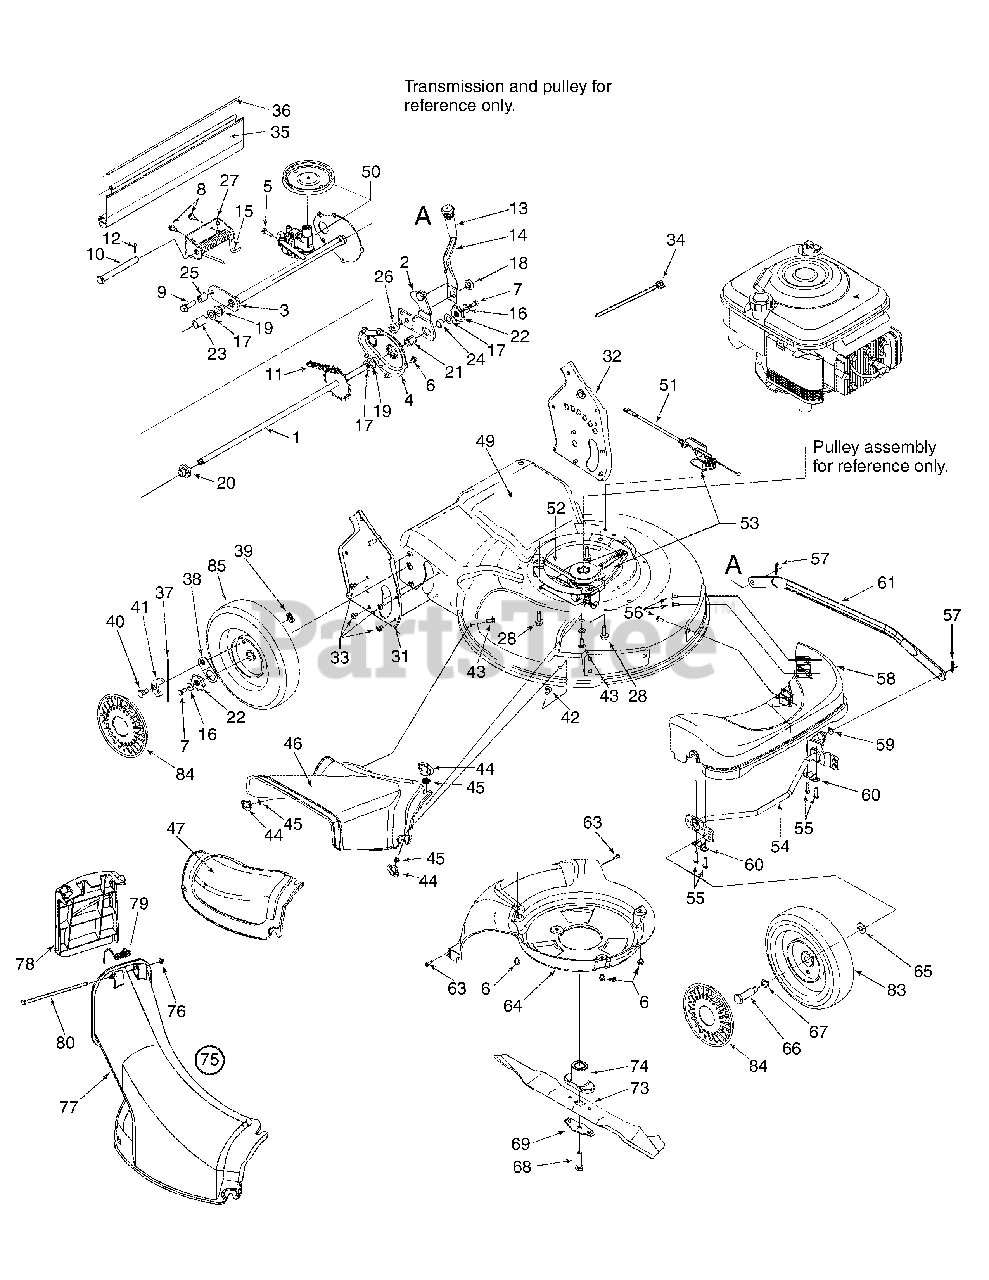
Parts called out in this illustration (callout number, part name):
1	Axle Ass’y 20T x 21.46" Lg.
6	Hex Wash HD Tapp Scr 1/4-20 x .38
7	Hex Bolt 1/4-20 x .62
8	Hex Wash HD. TT Tap Scr. 1/4-20 x .62
9	TT Screw 3/8-16 x 1.25
10	Clevis Pin .5" Dia. x 4.62" Lg.
11	Chain, No. 48 Endless .50 x 24 links
15	RH Torsion Sprocket
16	Cupped Wash. .25 ID x .88 OD x .062
17	Washer, Flat .505 ID x 1.0
18	Shoulder Nut .625 DIA. x .165
19	Flange Bearing .506 ID
20	Hex Flange Bearing
21	Hex Sleeve Bearing .504 x .830 Lg.
22	Ratchet Wheel
23	Spacer .55 ID x .75
24	Sleeve .511 id x .70 od x .37" lg.
25	Spacer .38 x .625" Lg.
26	Shoulder Spacer .385 ID x .715" Lg.
29	Hex Wash Hd Screw 10-32 x 5/8
30	Clamp Casing - Throttle
35	Rear Flap 17.25" Lg.
36	Rear Flap Wire
37	Spring Nylon
38	Pawl Plate
39	Toplock Flat Weldnut 1/4-20
40	Shoulder Screw .340 x .285: 1/4-20
42	Carriage Bolt 1/4-20 x .62
43	Carriage Bolt 1/4-10 x .75
44	Wing Nut
45	Bolt Retainer 1/4" x .50" OD
47	Mulching Baffle
51	SP Cable 51.0" Lg.
52	V-Belt 3/8 x 39.24" Lg.
55	Hex Wash. Hd. B-Tap Scr. 1/4 x 1.0" lg
56	Torx Hd. Scr. 5/16 x .75
57	Int. Cotter Pin 5/16 DIA
58	Front Cover- Yellow
58	Front Cover- Grey
58	Front Cover- Black
59	Bowed Washer
60	Bushing Block .505 dia.
63	Screw 1/4-15 X .75
64	Baffle
65	Cupped Wash .400 ID x .88 OD x .06
67	Wave Washer .51" ID
68	Hex Bolt 3/8-24 x 2.5" Lg.
69	Bell Blade Support
73	Blade 21"
74	Blade Adapter
75	Chute Assembly
76	Push Cap .188 Rod
77	Top Chute
78	Chute Door
79	Torsion Spring
83	Front Wheel Ass'y 8 x 2.125
84	Hub Cap -Grey
84	Hub Cap - Beige
84	Hub Cap -Yellow
85	Rear Wheel Ass’y 9 x 2.125
86	Shroud - Yellow
